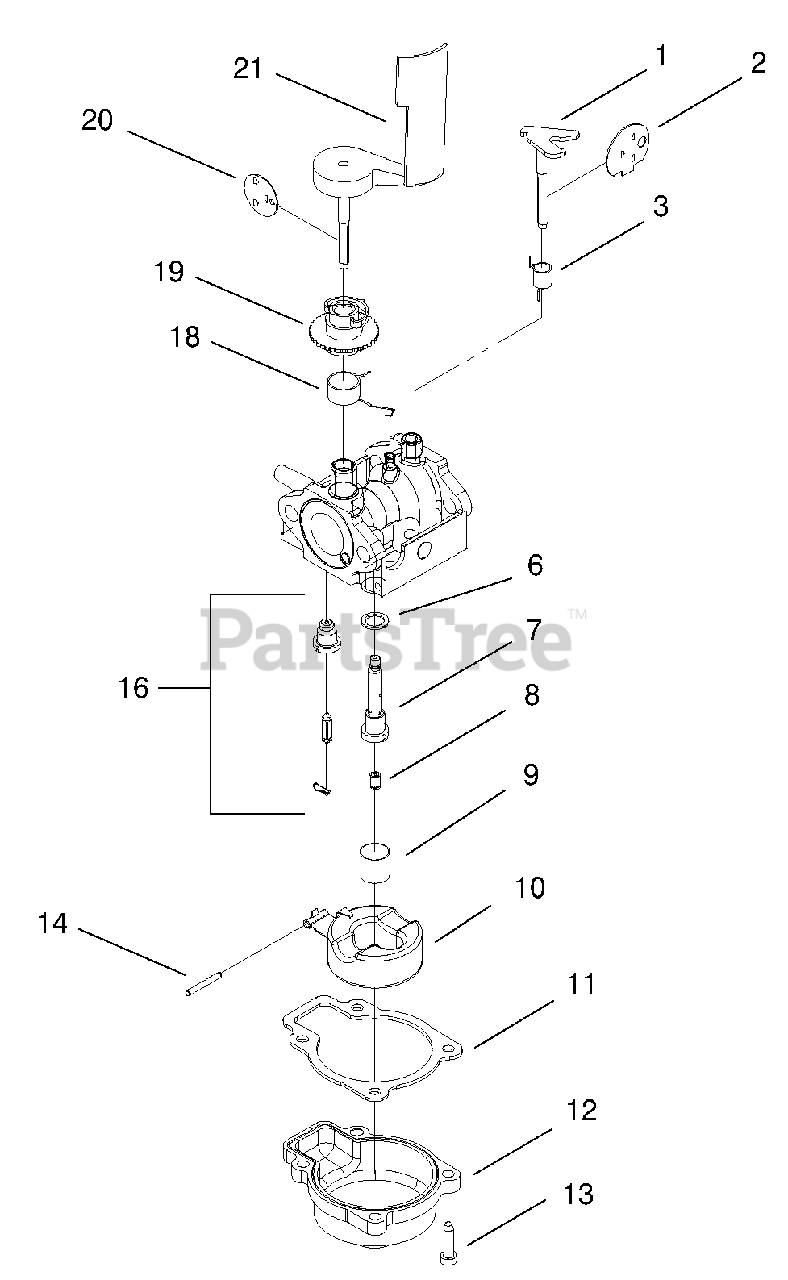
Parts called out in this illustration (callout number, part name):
1	SHAFT-CHOKE
2	DISC-CHOKE
3	SPRING-CHOKE
8	JET-MAIN 77.5
9	FILTER-FUEL
10	FLOAT AND ARM ASM
12	CHAMBER-FLOAT
13	SCREW-HH
14	PIN-STRAIGHT
16	VALVE / SEAT-FLOAT
18	SPRING-THROTTLE
19	COLLAR-ADJUST, AIRVANE
20	THROTTLE-DISC
21	AIRVANE AND SHAFT ASM
